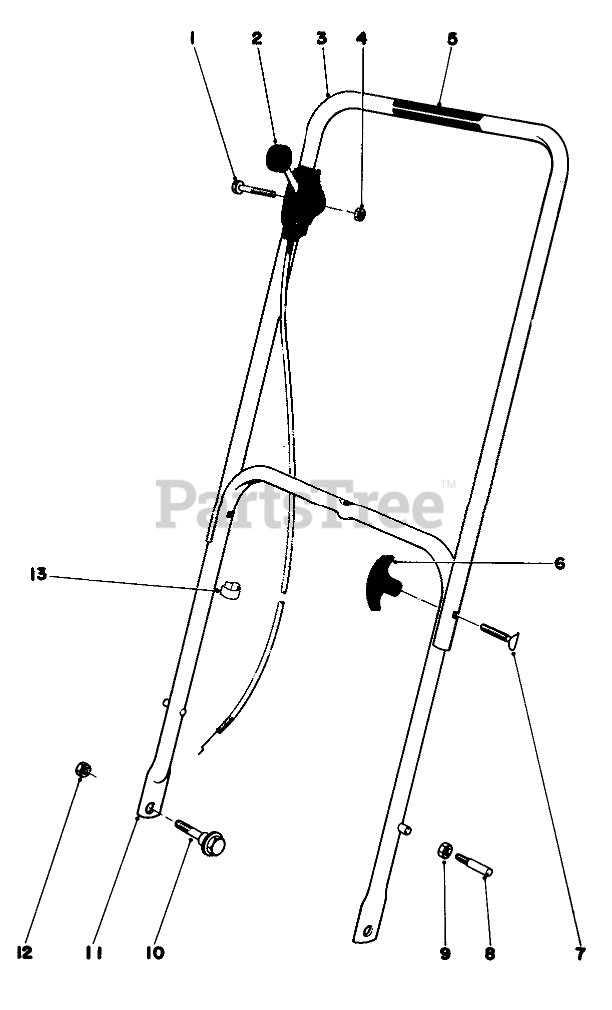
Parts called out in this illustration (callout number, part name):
1	SCREW-HH
2	Throttle Control
3	Upper Handle (Incl. Ref. #5)
4	NUT-LOCK
5	Decal
7	HANDLE SCREW
8	HANDLE PIN
9	Nut
10	SCREW-SHOULDER
11	19 LOWER HANDLE ASM
12	Nut
